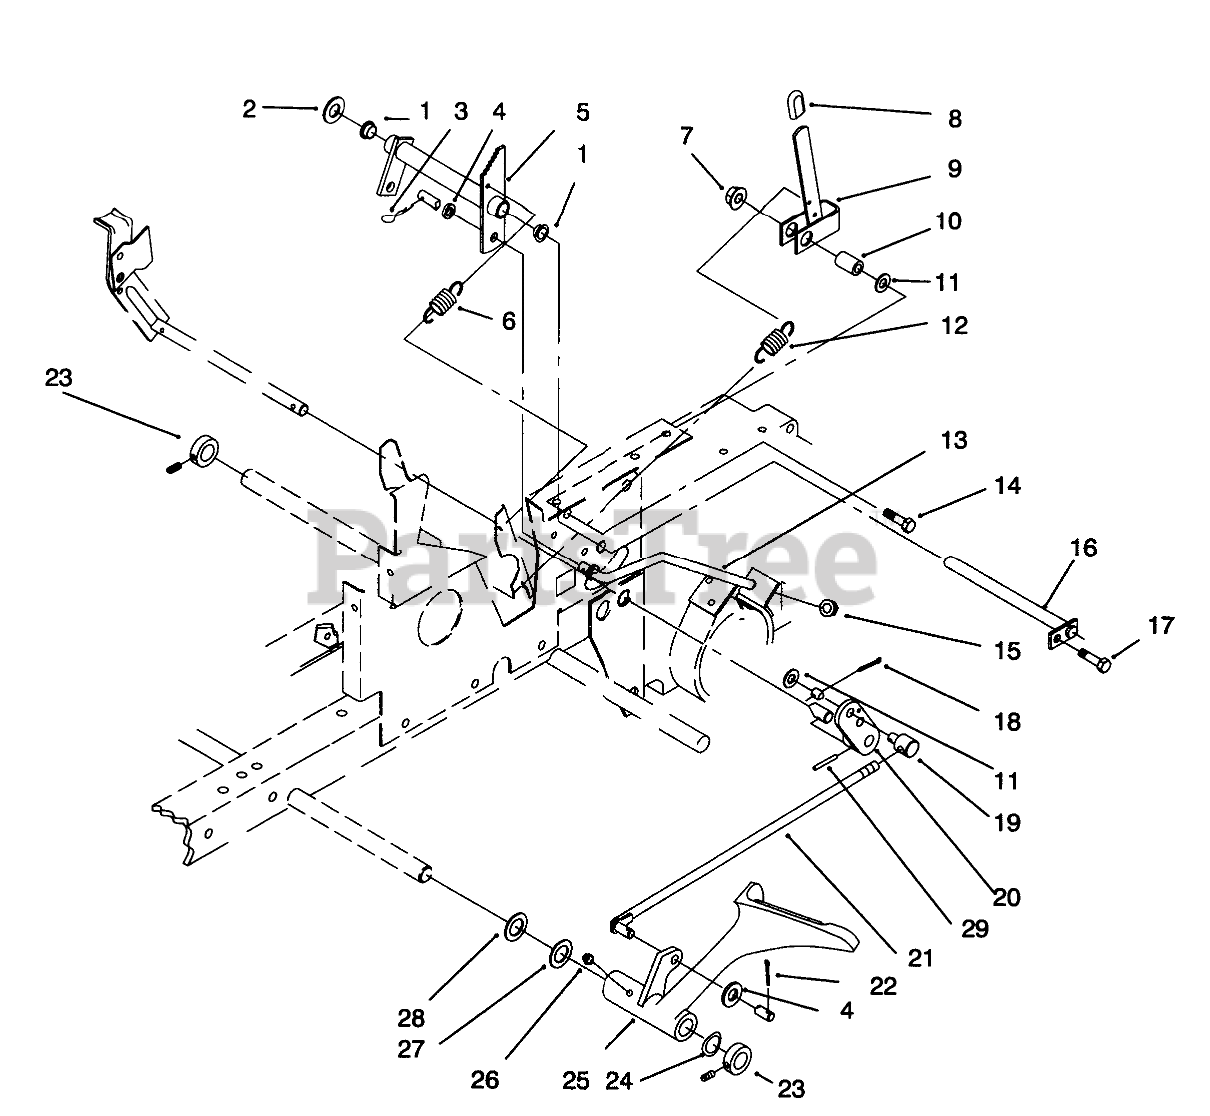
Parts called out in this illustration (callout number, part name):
1	BUSHING-FLANGED
2	WASHER-FLAT
3	PIN-HAIR
4	WASHER-NYLON
5	Bellcrank Assy
6	SPRING-EXTENSION
7	LOCKNUT-FLANGE
8	GRIP
9	ASSY-BRAKE LEVER WAB
10	SPACER
11	WASHER-FLAT
12	SPRING-BRAKE
13	ROD-REAR BRAKE
14	SCREW-HH
15	Belt-Drive
15	NUT-LOCK, NI
15	BELT-V IN
16	ROD ASM
17	Bolt
18	PIN-COTTER
19	TRUNNION
20	Arm-Clutch Rod
21	ROD AND GUIDE ASM
22	PIN-COTTER
23	COLLAR
24	WASHER-BOWED
25	Pedal-Clutch
26	FITTING-GREASE
27	WASHER
28	WASHER
29	PIN-SPIROL
30	SPRING-CLUTCH
